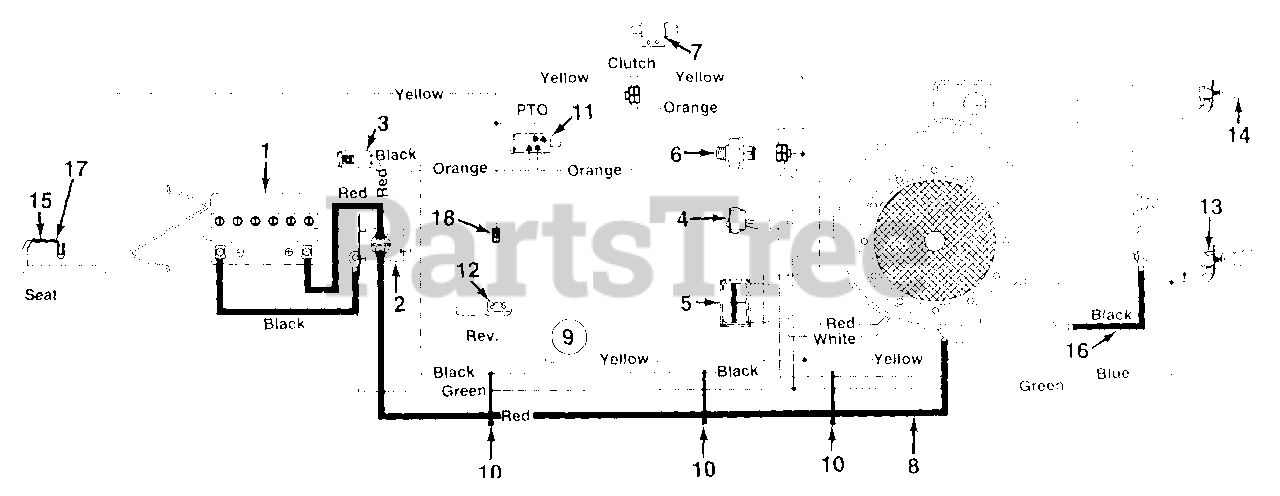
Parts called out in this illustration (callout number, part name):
1	Battery
2	Solenoid
3	Fuse 7.5 Amps
4	Light Switch
5	Ammeter
6	ignition Switch
7	Safety Switch (Clutch)
8	Electric Wire 30" Lg.
9	Wire Harness w/Ammeter
10	Cable Tie
11	Safety Switch (Deck)
12	Safety Switch (Reverse)
13	Socket
14	Bulb (Headlight)
15	Safety Switch (Seat)
16	Ground Wire 7.5" Lg.
17	Safety Switch (Seat)
18	Ext. Wire
